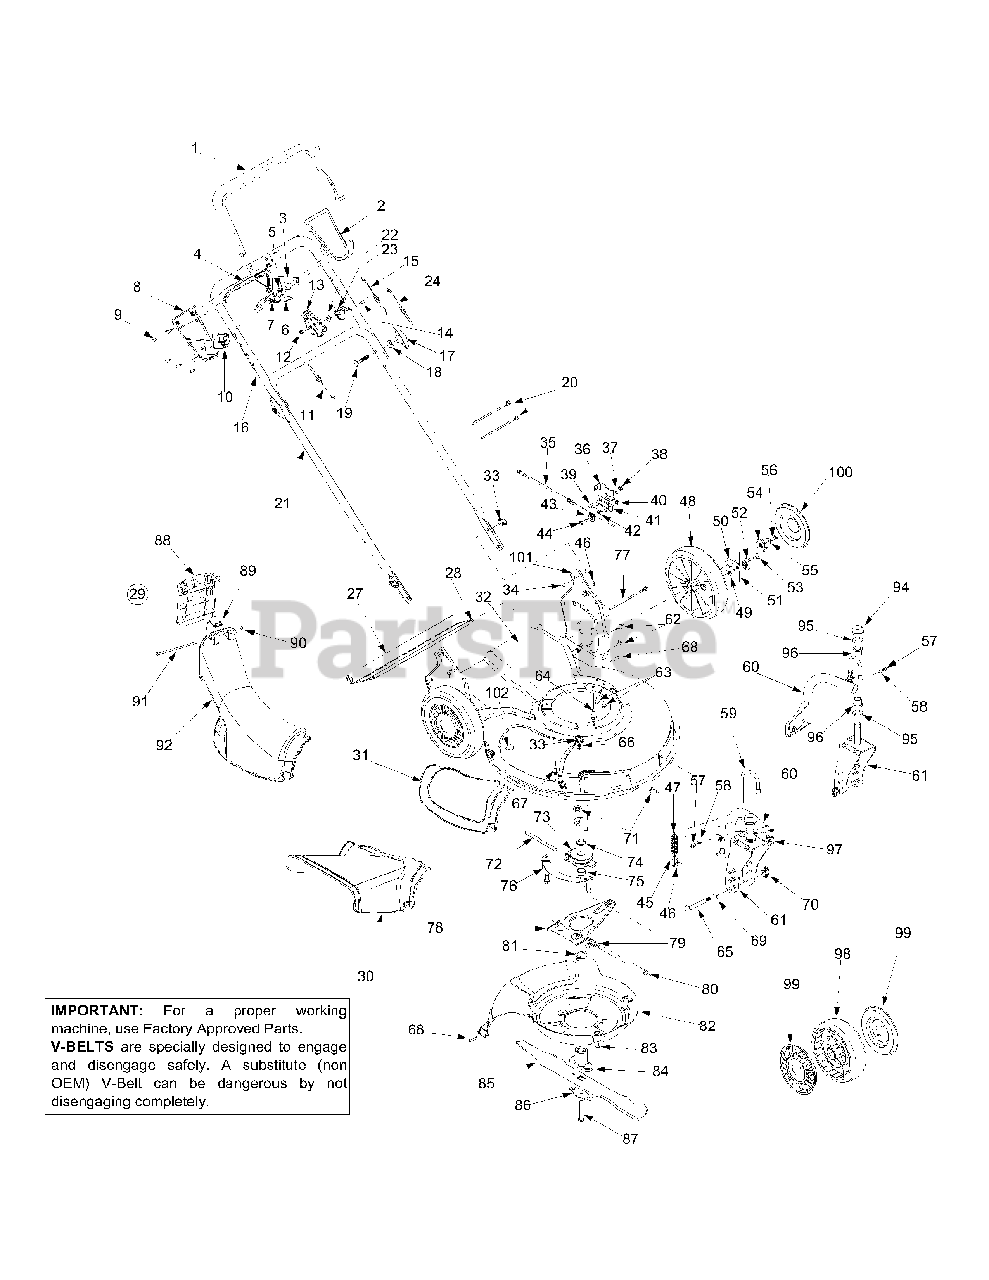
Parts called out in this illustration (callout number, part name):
1	Control Handle
2	Upper Control Housing
3	6 Spd. Rack Cable Bracket
4	Control Lever
5	Gear Insert
6	Shift Lever Spring
7	6 Speed Shift Lever
8	Lower Control Housing
9	C Sunk Tap Screw #10 x.75 Lg
10	Cable Mounting Cap
11	Drive Cable 51.0
12	Top Lock Nut 1/4-20
13	Control Housing
14	Mach. Screw
15	Control Cable
16	Upper Handle
17	Wing Nut
18	Saddle Washer.320 ID x.830 OD
19	Carriage Bolt 5/16-18 x 2.0
20	Cable Tie
22	Spring Washer
23	Choke Lever
24	Choke Cable
27	Trail Shield
28	Trail Shield Wire
29	Chute Assembly
30	Side-Discharge Chute
31	Mulch Cover
34	Carriage Bolt 1/4-20 x.75
35	6 Speed Cable
36	Cable Adjustment Bracket
37	Bell Washer.265 ID x.75 OD
38	Hex Nut 1/4-20
39	Carriage Screw 1/4-20 x.50
40	Hex Nut 1/4-28
41	Cable Mounting Bracket
42	Lock Washer 1/4
43	Cable Roller
44	Shoulder Screw.375 ID x 1/4-14
45	Flat Washer.330 ID x.630 OD
46	Cotter Pin
47	Compression Spring
48	Wheel 9 x 2
49	Top Lock Tab Weld Nut 1/4-20
50	Ratchet Pawl Plate
51	Plastic Spring Ratchet
52	Pawl RH
52	Pawl LH
53	Shld Screw.340 ID x.285 OD
54	Wheel Rachet
55	Bell Washer.265 ID x.75 OD
56	Hex Cap Screw 1/4-20 x.620
57	Grease Fitting
58	Flat Washer.203 ID x.403 OD
59	Wheel Pin Lock
62	Screw 1/4-14 x.500
63	Screw 1/4-20 x.625
64	Hex Washer Screw 3/8-16 x 1.0
65	Caster Axle
66	Push Nut.25ID x.50OD
67	Carriage Screw 1/4-20 x.75
68	Screw #12-16 x 1.00
69	Wave Washer.531 ID x.781 OD
70	Wing Nut
71	Carriage Bolt 5/16-18 x.62
72	Belt 3/8 x 39.24
73	Pulley Assembly
74	Sleeve Spacer.88 ID x 1.13 OD
75	Sleeve Spacer.88 ID x 1.00 OD
77	Cable Tie
80	Pivot Shaft
81	Wave Washer 1.38 ID x.88 OD
82	Baffle
83	Screw 1/4-20 x 3.75
84	Blade Adapter
85	21" Mulching Blade
86	Blade Bell Support
87	Hex Bolt 3/8-24 x 2.5
88	Chute Door
89	Torsion Spring
90	Push Cap
91	Pivot Rod
92	Discharge Chute
94	Push Cap
95	Flat Washer.640 ID x 1.12 OD
96	Flange Bearing
97	Flange Lock Nut 5/16-18
98	Wheel 7 x 2
99	Hubcap - Spoke w/ Hole
100	Hubcap - Radial Spoke
103	Engine Spacer
